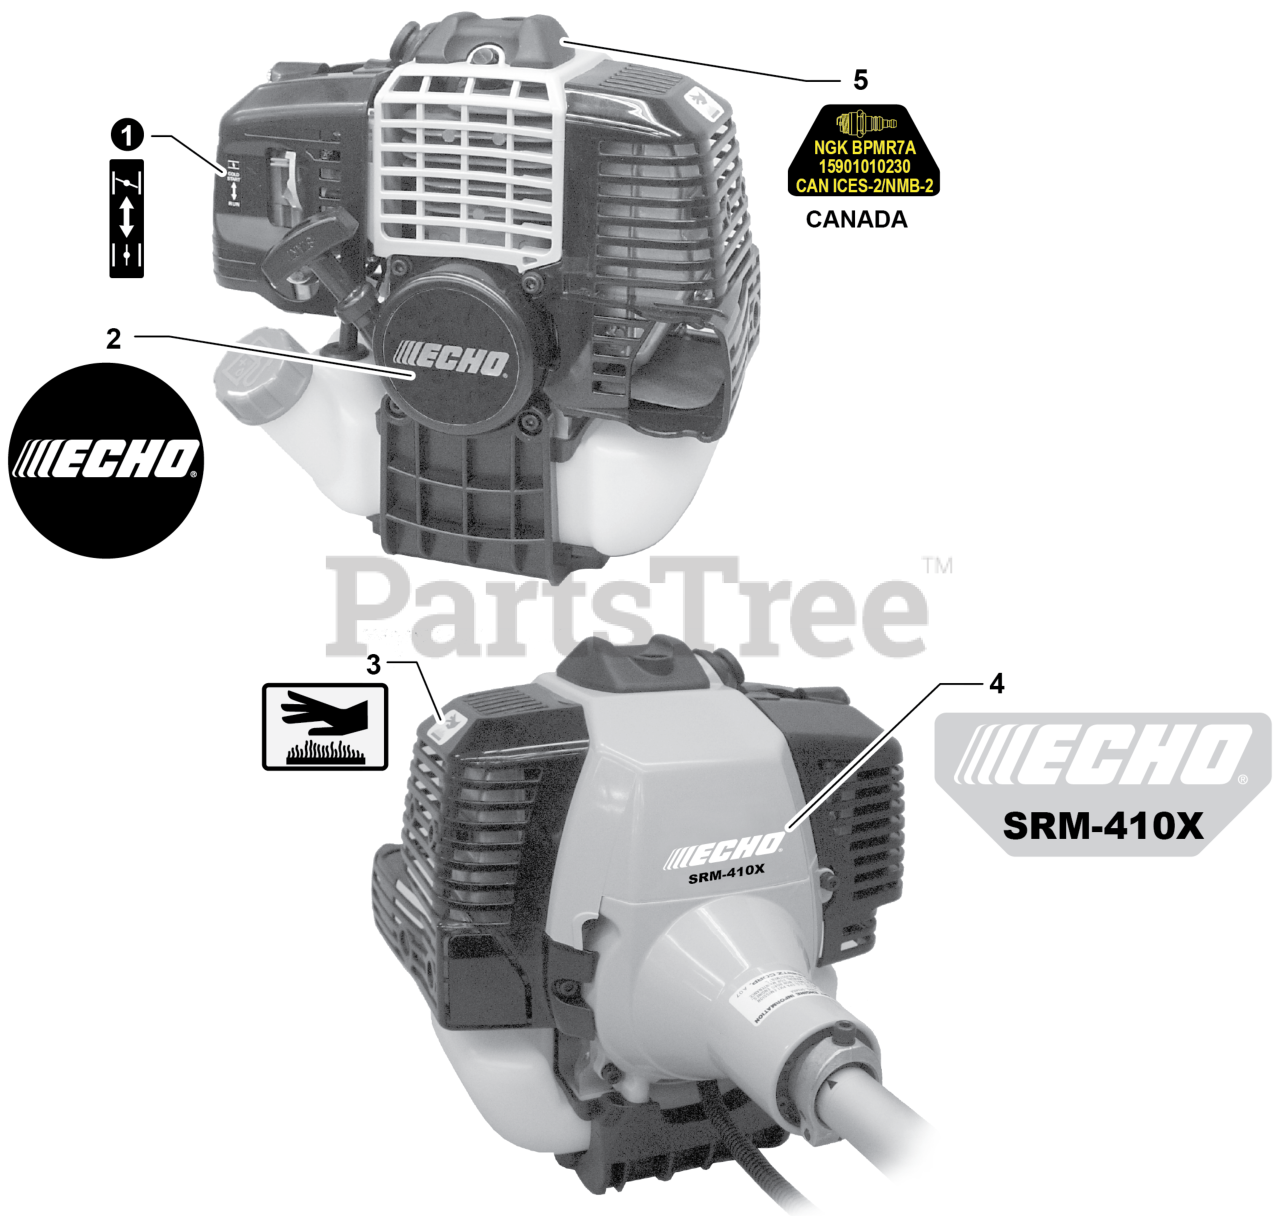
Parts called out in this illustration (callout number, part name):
1	LABEL - CHOKE
2	LABEL - STARTER - ECHO
3	LABEL - CAUTION - HOT
4	LABEL - MODEL - SRM-410X
5	LABEL - SPARK PLUG - BPMR7A
